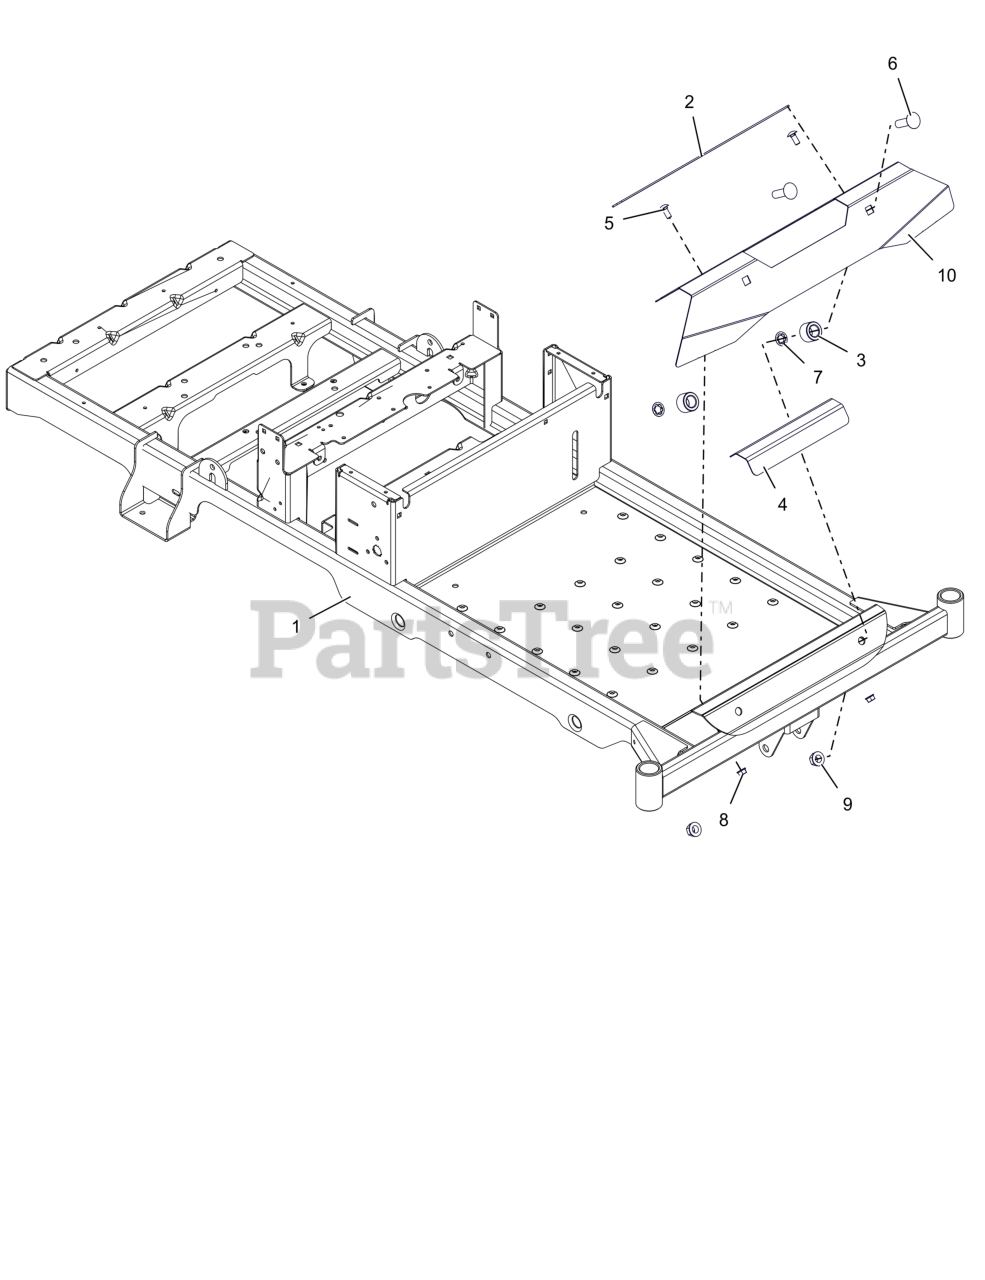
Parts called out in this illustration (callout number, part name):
1	KIT, ZT FRAME W/DECALS
2	GRIP, ADHESIVE (1" X 16" BLK)
3	TUBE, UPPER CONTROL PIVOT
4	GRIP, STEP
5	BLT, RHSSN.31-18X.750 G5 ZCC
6	BLT,RHSN .50-13X1.75 G5 ZCC
7	NUT-PUSH, .50
8	NUT,LK-CTR-FLG .31-18 GF ZCC
9	NUT-LK-CTR-FLG .500-13 GG ZCC
10	FOOTREST, GRAVELY (RED)
